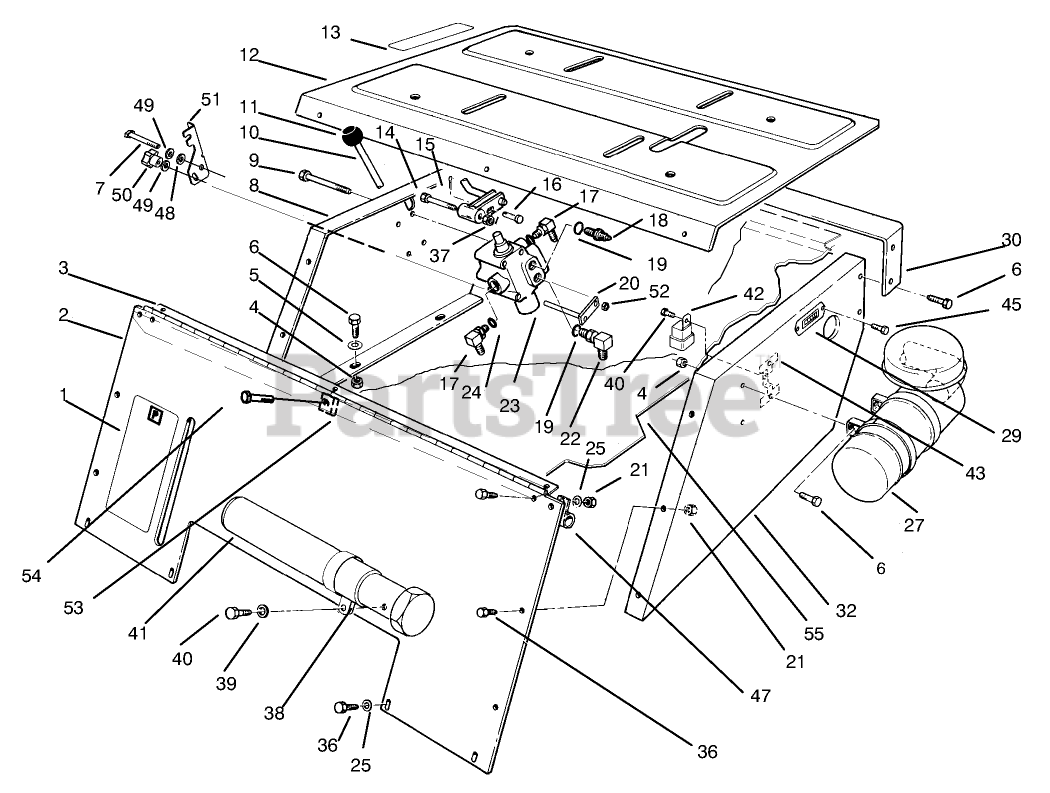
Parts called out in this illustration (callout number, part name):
1	DECAL - PARKING BRAKE
2	Support-Seat, Front
3	Hinge-Seat
4	NUT-LOCK, NI
5	WASHER-PLAIN
6	SCREW-HH
7	SCREW-HH
8	Support-Seat RH.
9	SCREW-HH
10	Lever-Valve
12	Plate-Seat
13	DECAL - LIFT CONTROL
14	BOLT-WHEEL
15	PIN-COTTER
16	PIN-CLEVIS
17	FITTING-HYD, 90 DEG
18	FITTING-STRAIGHT
19	O-RING
20	WA - CONTROL BLOCK
21	NUT-LOCK, NI
22	FITTING-ELBOW, 90
23	VALVE ASM
24	O-RING
25	WASHER-FLAT
27	AIR CLEANER KIT
29	HOURMETER
30	Support-Hood
32	Support-Seat L.H.
36	SCREW-HH
37	NUT-HEX
38	CLAMP-R
39	WASHER-FLAT
40	SCREW-HWHTF
41	TUBE-MANUAL
42	RELAY
43	Bracket
45	SCREW-HWH
47	CLAMP-R
48	SPACER - LATCH
49	WASHER-FLAT
50	KNOB-CHUTE
51	BRACKET - HYDRO LOCK
52	NUT-LOCK, NI
53	NUT-SPEED
54	SCREW-HH
55	Cover-Belt
